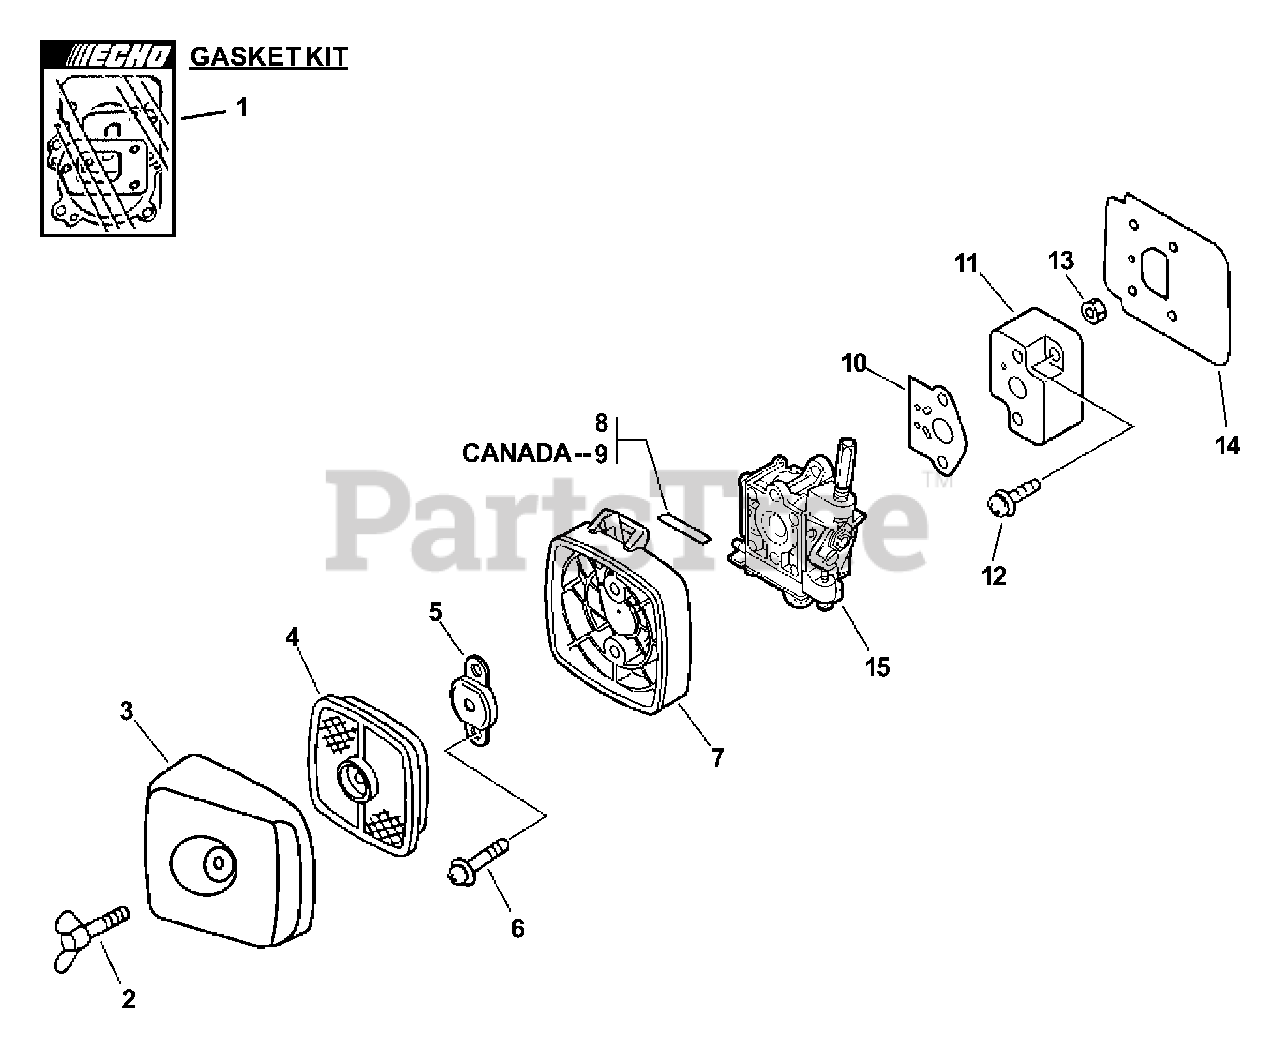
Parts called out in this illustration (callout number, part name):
1	GASKET KIT
2	BOLT, WING 5×20
3	COVER, AIR FILTER - GRAY
4	FILTER, AIR - SINGLE LAYER
5	PLATE, PREVENT
6	SCREW 5×65
7	CASE, AIR FILTER - GRAY
8	LABEL, CHOKE
9	LABEL, CHOKE
10	GASKET, CARBURETOR
11	INSULATOR, INTAKE
12	SCREW 5×20
13	NUT M5
14	HEAT SHIELD, INTAKE
15	CARBURETOR
